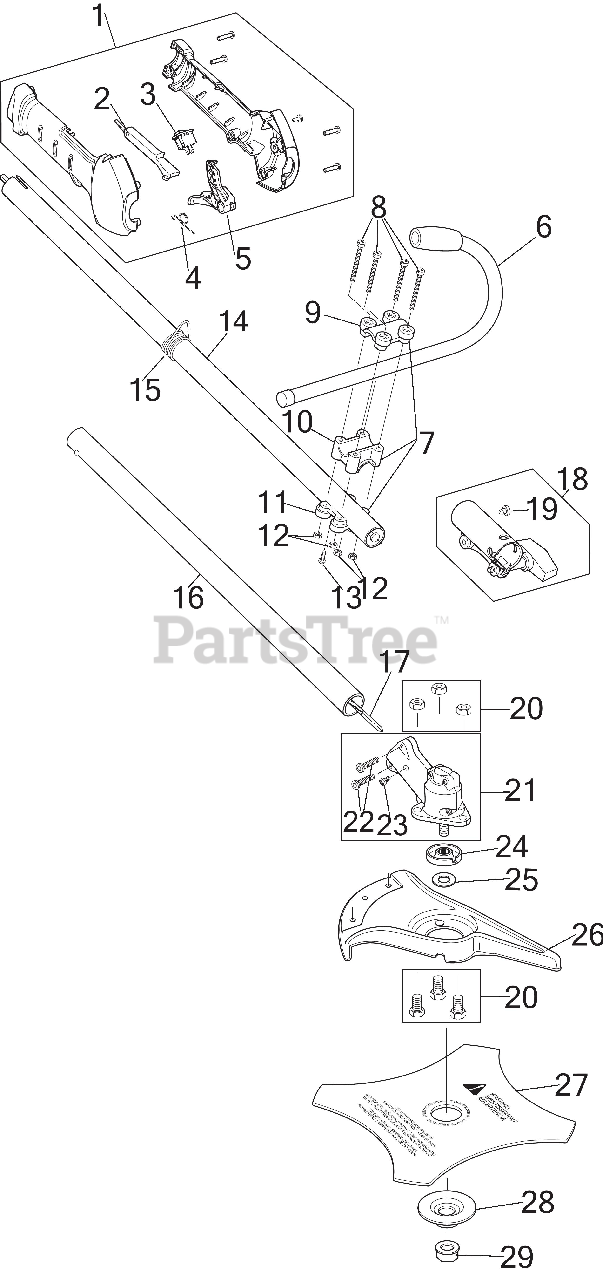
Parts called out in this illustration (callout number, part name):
1	THROTTLE GRIP ASSEMBLY
2	LOCK OUT LEVER
3	SW, MOMENTARY ON/O
4	SPRING TRIG
5	THROTTLE TRIGGER
6	ASSEMBLYMY, J-HANDLE W/
7	HANDLE BRACKET ASSEMBLY
8	SCREW-CLAMP
9	CLAMP-HANDLE UPPER
10	CLAMP-HANDLE MIDDLE
11	CLAMP-HANDLE LOWER
12	NUT-CLAMP
13	SCREW, 8-32 x .312 P
14	UPPER DRIVE SHAFT HOUSING ASSEMBLY
15	CLAMP-SHOULDER STR
16	ASSEMBLY, LOWER DRIVE S
17	LOWERIBLE DRIVE SHAFT
18	CLICK LINK ASSEMBLY SRS
19	SCREW, 10-32X.250 TA
20	SCREW SET-GUARD MT
21	GEARBOX ASSEMBLY
22	SCREW #
23	SCREW, 8-32 x .312 P
24	SPACER-GEARBOX
25	PALNUT:3/8" DIAMET
26	SHIELD-BLADE CAST
27	BLADE 4-TOOTH
28	WASHER-BLADE CLAMP BRUSH CUT
29	BLADE LOCK NUT
